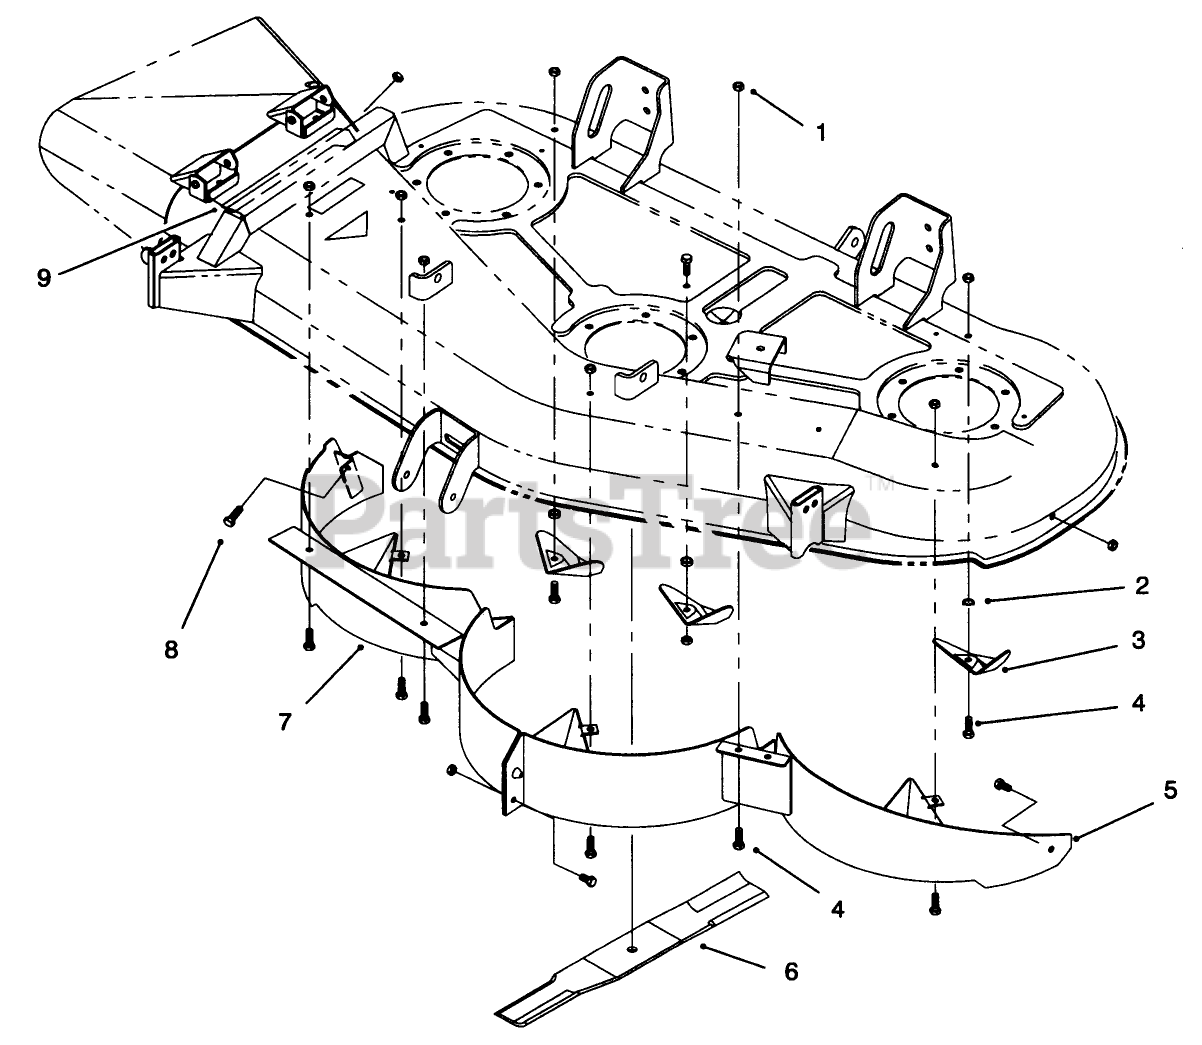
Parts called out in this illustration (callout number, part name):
1	NUT-LOCK, NI
2	SPACER
3	PLATE-KICKER
4	SCREW-HH
5	LEFT BAFFLE ASM
6	BLADE
7	RIGHT BAFFLE ASM
8	SCREW-HH
9	DECAL-DECK
